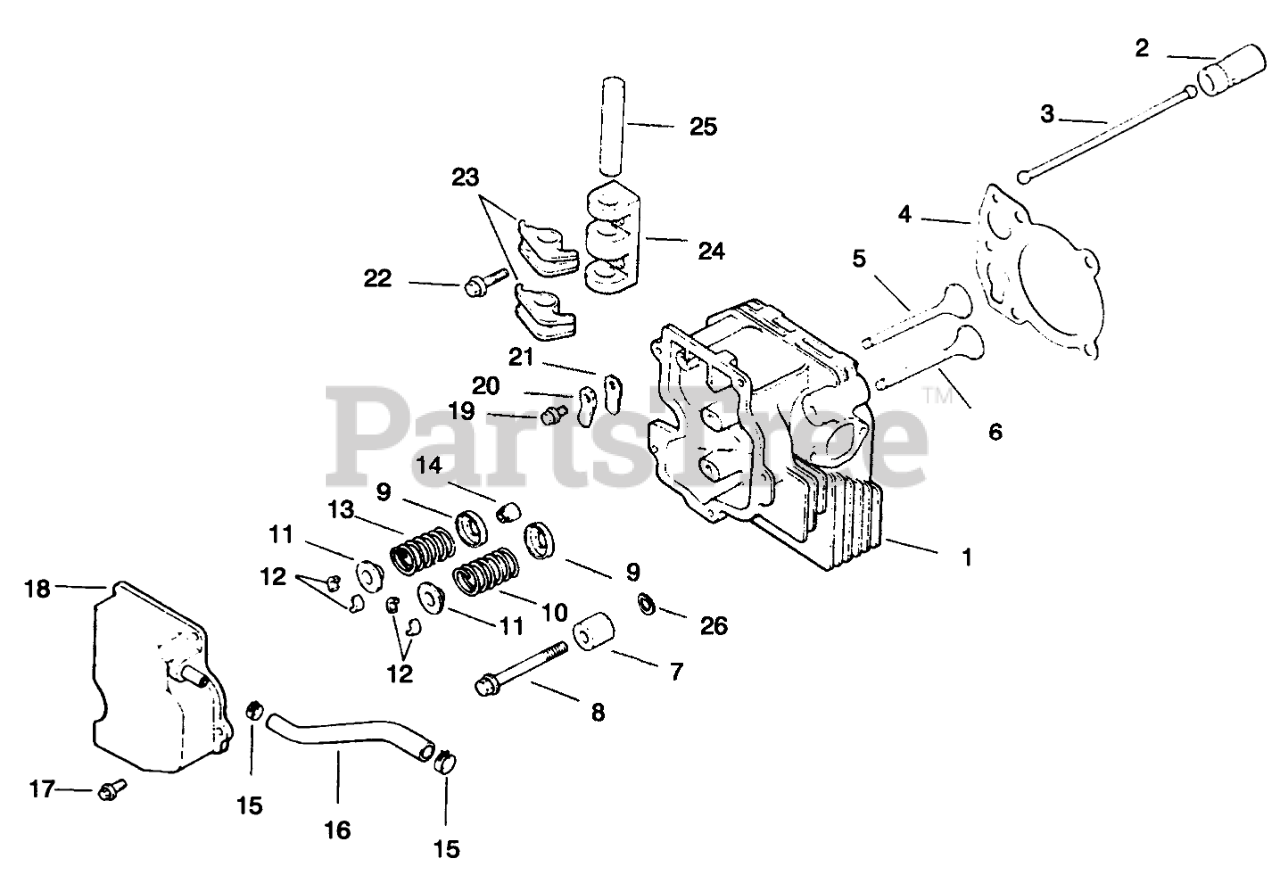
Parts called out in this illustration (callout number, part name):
1	Cylinder Head
2	Lifter-Valve
3	Rod-Push
4	Gasket-Cylinder Head
5	Valve-Intake (Std.)
6	Valve-Exhaust (Std)
7	Spacer-Head Bolt
8	Screw-Cylinder Head
9	Retainer-Spring
10	Spring-Valve
11	Cap-Valve spring
12	Kit-Retainer
13	Spring-Valve, Exhaust
14	Seal-Valve Stem
15	Clamp
16	Hose-Breather
17	Screw
18	Cover-Valve W/Nipple
19	Screw
20	Retainer-Breather Reed
21	Reed-Breather
22	Screw
23	Arm-Rocker
24	Bridge-Rocker Arm
25	Shaft-Rocker Arm
26	Washer-Flat
